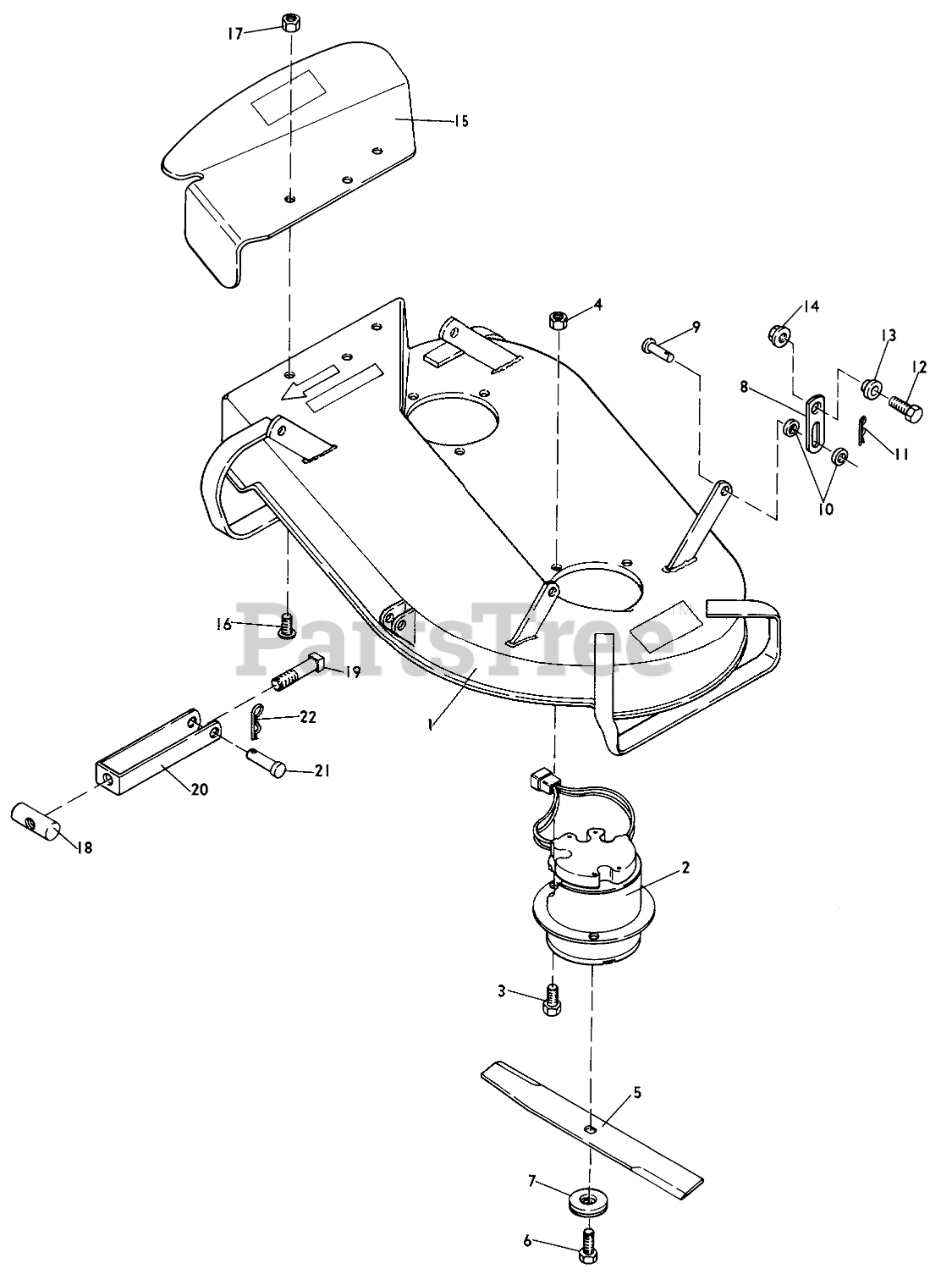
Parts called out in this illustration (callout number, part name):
1	Mower Deck Assembly
2	Blade Motor
3	HHCS
4	Nut
5	Blade (Two Blade Kit)
6	H H C S
7	Washer Assembly
8	BAR-LIFT LINK R
9	Pin
10	WASHER-NYLON
11	Hairpin Cotter
12	BOLT
13	SPACER-LIFT LINK
14	LOCKNUT-FLANGE
15	Chute Extension
16	SCREW
17	Nut
18	Front Trunnion
19	Bolt, 1/2-13 x 2 3/4 Sq. Hd.
20	Clevis
21	Clevis Pin
22	Hairpin Cotter
